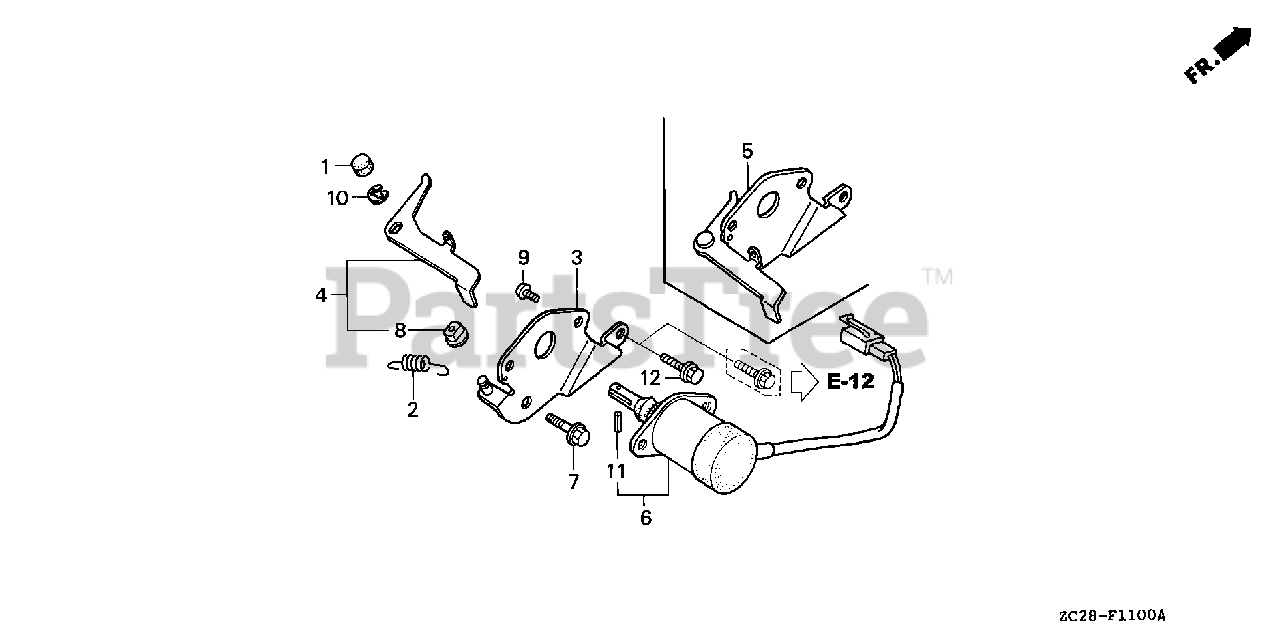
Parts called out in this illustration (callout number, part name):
2	SPRING, CHOKE RETURN
5	LEVER, THROTTLE
6	SOLENOID ASSY.
7	BOLT, FLANGE (6X12) (CT200)
9	SCREW, PAN (5X8)
11	PIN, SPRING (2.5X16)
12	BOLT, FLANGE (6X12) (CT200)
